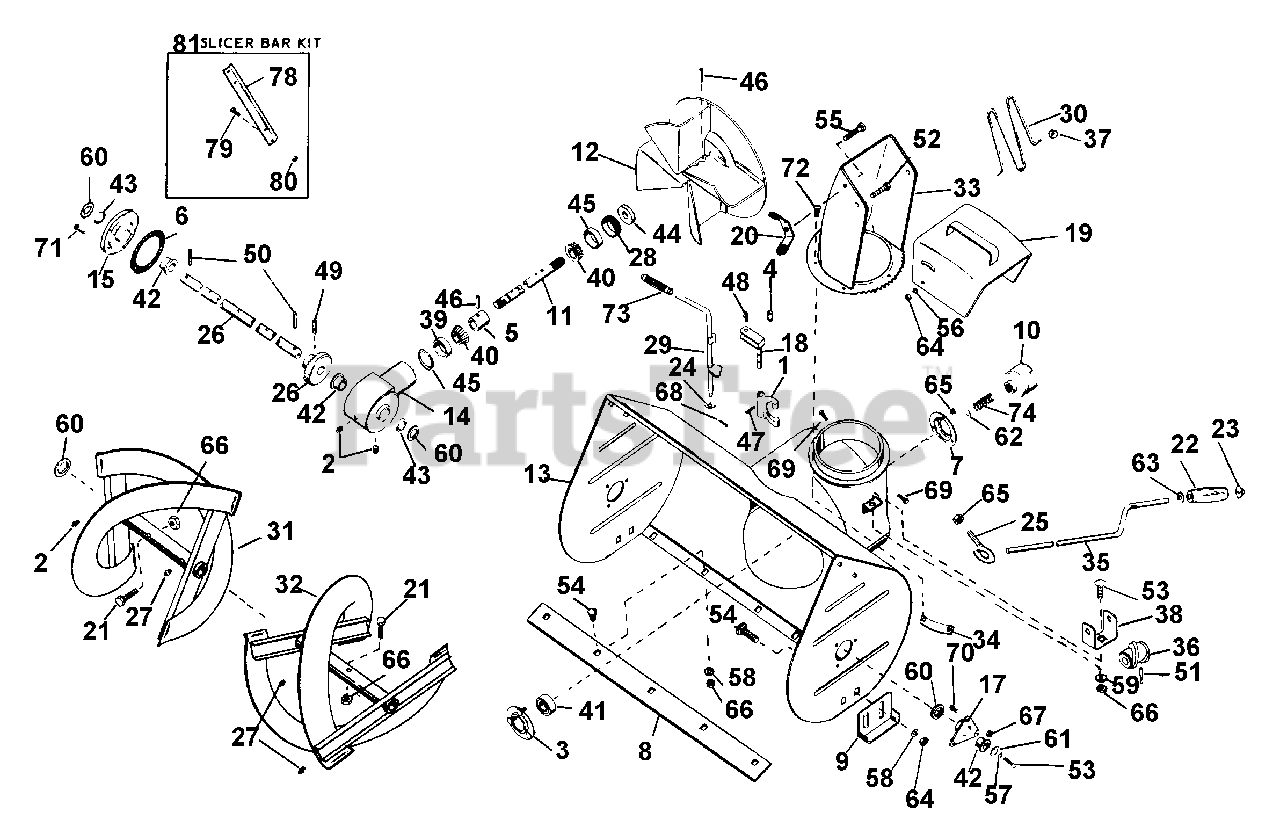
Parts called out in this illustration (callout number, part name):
1	CLUTCH FORK
2	PIPE PLUG
3	BEARING FLANGE
5	BEARING SPACER
7	BEARING FLANGE
8	SCRAPER BLADE 24"
9	RUNNER
10	JAW CLUTCH
11	HELICON PINION SHAFT
13	BLOWER HOUSING
14	CASE, GEAR - C.I.
15	GEAR CASE FLANGE
16	HELICON GEAR - 41 TOOTH
17	BEARING SUPPORT
18	FORK SHAFT
19	DEFLECTOR CHUTE
20	WING NUT
21	SHEAR BOLT YWZC
23	CAP, 3/8 ROD YWZC
24	WAVE WASHER .406X.750X.063FH
25	ROD HANGER EYEBOLT
26	FRONT GEAR SHAFT
27	HYDRAULIC DRIVE FITTING
28	ADJUSTMENT PLUG
29	FORK CAM
30	SAFETY WIRE
31	RAKE, RIGHT-24"(1ID X 15.88OD)
32	RAKE, LEFT-24"(1"ID X 15.88OD)
33	DISCHARGE CHUTE
34	CHUTE CLAMP
36	WORM GEAR
37	FASTENER
38	WORM CLEVIS
39	BRG-CUP 1.781X.475
40	BRG-CONE .750X.61
41	BRG-BALL .750X1.750X.50
42	BSHG-FLG 1.000X1.12X.62X1.50BR
43	SEAL 1.000X1.312X.150
44	SEAL .750X1.499X.225
45	RG-RTNG INT 1.781 HSG X.062
46	PIN-ROLL .250X1.25
47	PIN-ROLL .188X1.00
48	PIN-ROLL .313X1.25
49	PIN-ROLL .313X1.38
50	PIN-ROLL .188X1.50
51	PIN-ROLL .125X.75
52	BLT-HEX .38-16X.75 PL GR2
53	BLT-HEX .50-13X1.00 PL GR2
54	BLT-RDHDSQSHNK .31-18X.50 YZ
55	BLT-RDHDSQNK .38-16X.75 SHT PL
56	WSHR-LK .375X.115 HVY PL
57	WSHR-LK .500X.151 HVY PL
58	WSHR-FL-STL .38X.875X.083 PL
59	WSHR-FL-STL.312X.734X.065PL
60	WSHR-FL-STL 1.010X1.505X.062PL
61	WSHR-FL-STL .511X1.441X.125 PL
62	WSHR-FL-STL .755X1.375X.062 PL
63	WSHR-FL-STL .382X.812X.023 PL
64	NUT-LK-CTR .375-16 GR A PL
65	NUT-LK-CTR .250-20 PL
66	NUT-LK .312-18 GR A PL
67	NUT-LK-FLG .250-20 PL
68	PIN-COTR .12X1.0 PL
69	BLT-SCRHFWH .38-16X.50 PL
70	SCR-SLTR-SERNK .25-20X.62 PL
71	BLT-SERHFWH .25-20X.75 PL
72	SCR-TAP 10-24X.375 CRPH 1A
74	SG-COMP .105X1.35X1.984
75	SNO-THRO DECAL
76	CAUTION LABEL
77	CLUTCH INSTRUCTION DECAL
78	CUTTER BAR
79	BLT-RDHDSQSHNK .31-18X.50 YZ
80	NUT-LK .312-18 GR A PL
81	SLICER BAR KIT
